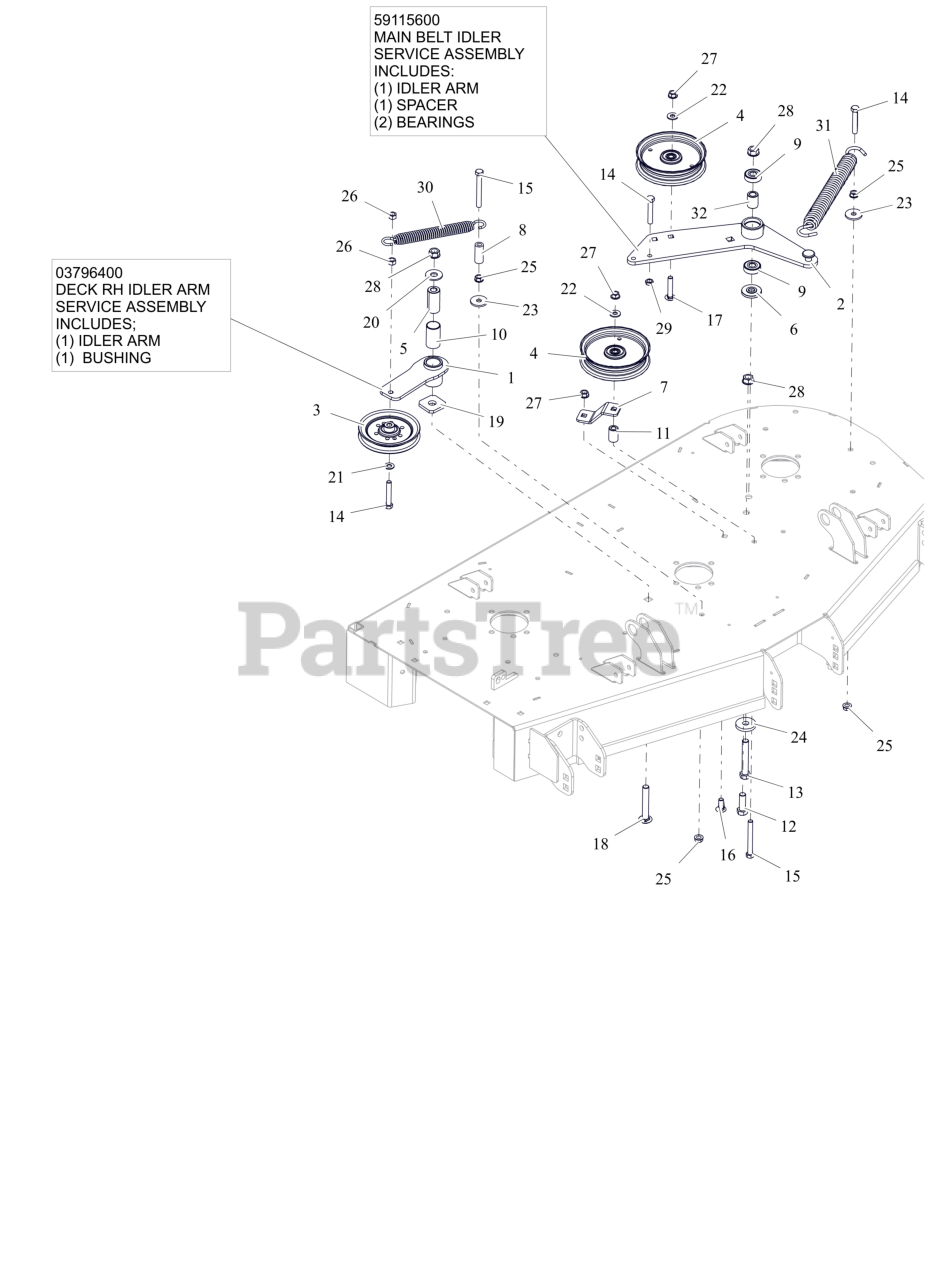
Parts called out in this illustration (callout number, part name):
1	WMT, IDLER ARM - BLACK
1	ASM, IDLER ARM (DECK)
2	WLDMT, DECK PTO IDLR ARM
2	ASSEMBLY, MAIN BELT IDLER
3	IDLER, V, 5.00X.38
4	IDLER- FLAT - 5.00" X .75"
5	BSHG, SPCR .502X.997X2.03 PM
6	SPACER, IDLER ARM
7	PTO FIXED IDLER MTG BRKT-ORG
8	HOSE, .38 X 1.65
9	BRG-BALL .500X1.38X.437
10	BSHG, 1.00X1.125X1.937
11	BUSHING, SLV .380X.750X1.190
12	BLT,HEX .50-13X1.50 G5 ZCC
13	BLT,HEX .50-13X3.25 G5 ZCC
14	BLT,HEX .38-16X2.25 G5 ZCC
15	BLT, HEX .38-16X3.25 G5 ZCC
16	BLT,RHSSN .38-16X1.00 G5 ZCC
17	BLT,RHSSN.375-16X2.00 G5 ZCC
18	BTL,RHSSN .500-13 X 3.25 G5 ZCC
19	WSHR-FLT .640X1.75X.250
20	WSHR,FLT .563X1.375X.109 ZCC
21	WSHR,FLT .406X.812X.065 ZCC
22	WSHR,FLT .375X.875X.083 ZCC
23	WSHR,FLT .406X1.375X.135 ZCC
24	WSHR-FL-STL .515X1.625X.250 YZ
25	NUT, SPNLK-FLG .38-16 G5 ZCC
26	NUT-LK-CTR .38-16 ZC120
27	NUT-LK-CTR-FLG .375-16 GF ZCC
28	NUT-LK-CTR-FLG .500-13 GG ZCC
29	NUT-JAM .375-16 G2 ZCC
30	SPRING- EXTENSION
31	SPRING, EXTENSION
32	SPACER .510 X .867 X 1.1485
